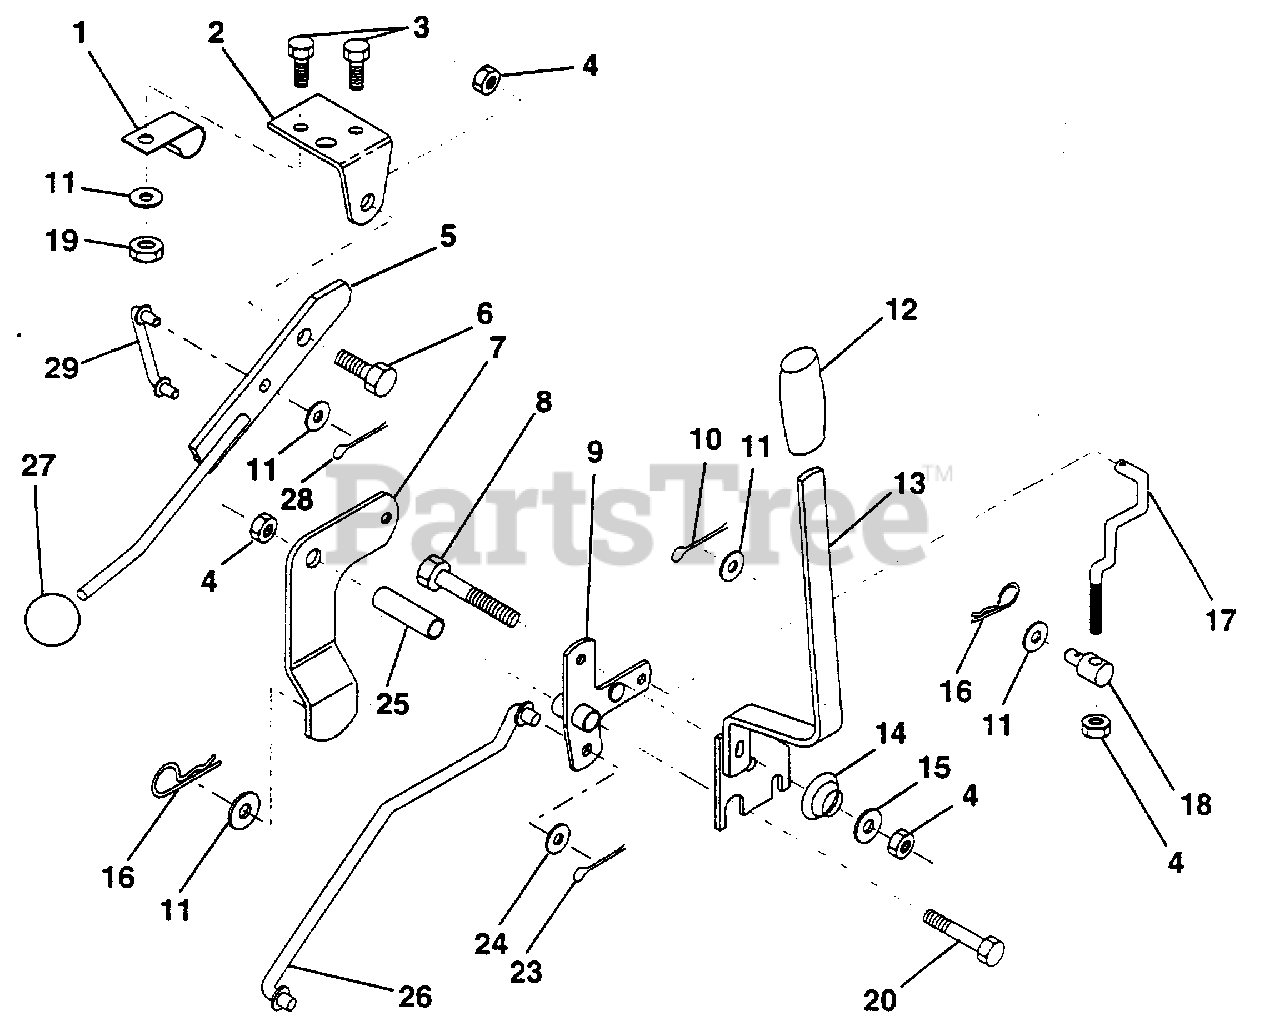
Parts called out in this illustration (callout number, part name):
1	Clip, Insulated
2	Bracket, Mower Clutch
3	Bolt, Fin Hex 1/4-20 UNC x 1/2 Gr. 5
4	Nut, Crownlock 3/8-16 UNC
5	Assembly, Clutch Lever
6	Bolt, Shoulder
7	Assembly, Mower Clutch Arm
8	Bolt, Hex 3/8-16 UNC x 2-1/4
9	Assembly, Bracket Lift
10	Pin, Cotter 1/8 x 3/4
11	Washer 13/32 x 13/16 x 16 Ga.
13	Assembly, Lift Handle
14	Spring, Compression
15	Washer 13/32 x 3/4 x 12 Ga.
16	Retainer, Spring
17	Link, Front Lift
18	Trunnion, Threaded 3/8-16
19	Nut, Crownlock 1/4-20
20	Bolt, Fin Hex 3/8-16 UNC x 2-3/4
23	Pin, Cotter 1/8 x 1
24	Washer 17/32 x 1 x 16 Ga.
26	Rod, Mower Lift
28	Pin, Cotter 3/32 x 3/4
29	Link, Mower Clutch
